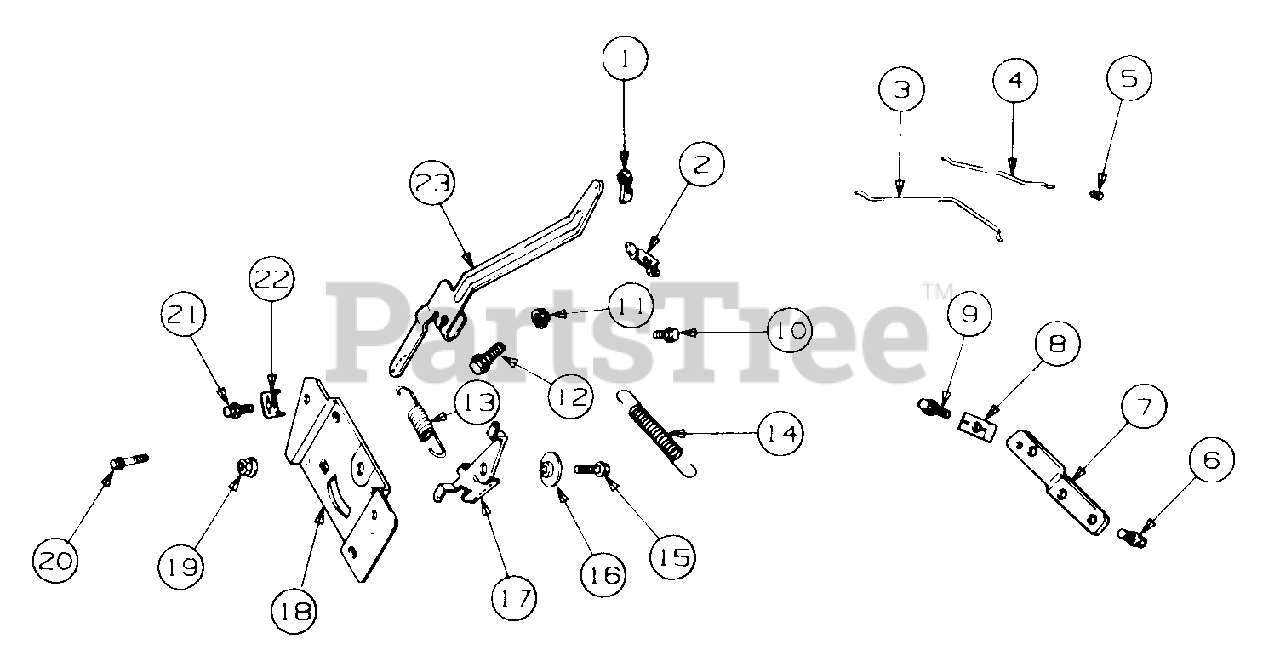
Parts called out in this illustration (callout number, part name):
1	Bushing, Throttle
2	Lever, Choke, Upper
3	Linkage, Choke, Upper
4	Linkage, Throttle
5	Bushing, Linkage
6	Screw, Bracket, M5 x 0.8 x 10
7	Bracket, Choke Mount
8	Clamp, Cable
9	Screw, Clamp, M5 x 0.8 x 16
10	Screw, M5 x 0.8 x 10
11	Nut, M6 x 1.0
12	Screw, Gov Arm, M6 x 1.0 x 25
13	Spring, Governor
14	Spring, Linkage
15	Screw, Throttle Control M5 x 0.8 x 16
16	Spacer, Throttle Control
17	Lever, Throttle Control
18	Plate, Control
19	Nut, Hex, M5 x 0.8
20	Screw, Control Plate, M6 x 1.0 x 16
21	Screw, Cable Clamp, M5 x 0.8 x 16
22	Clamp, Cable
23	Lever, Governor
